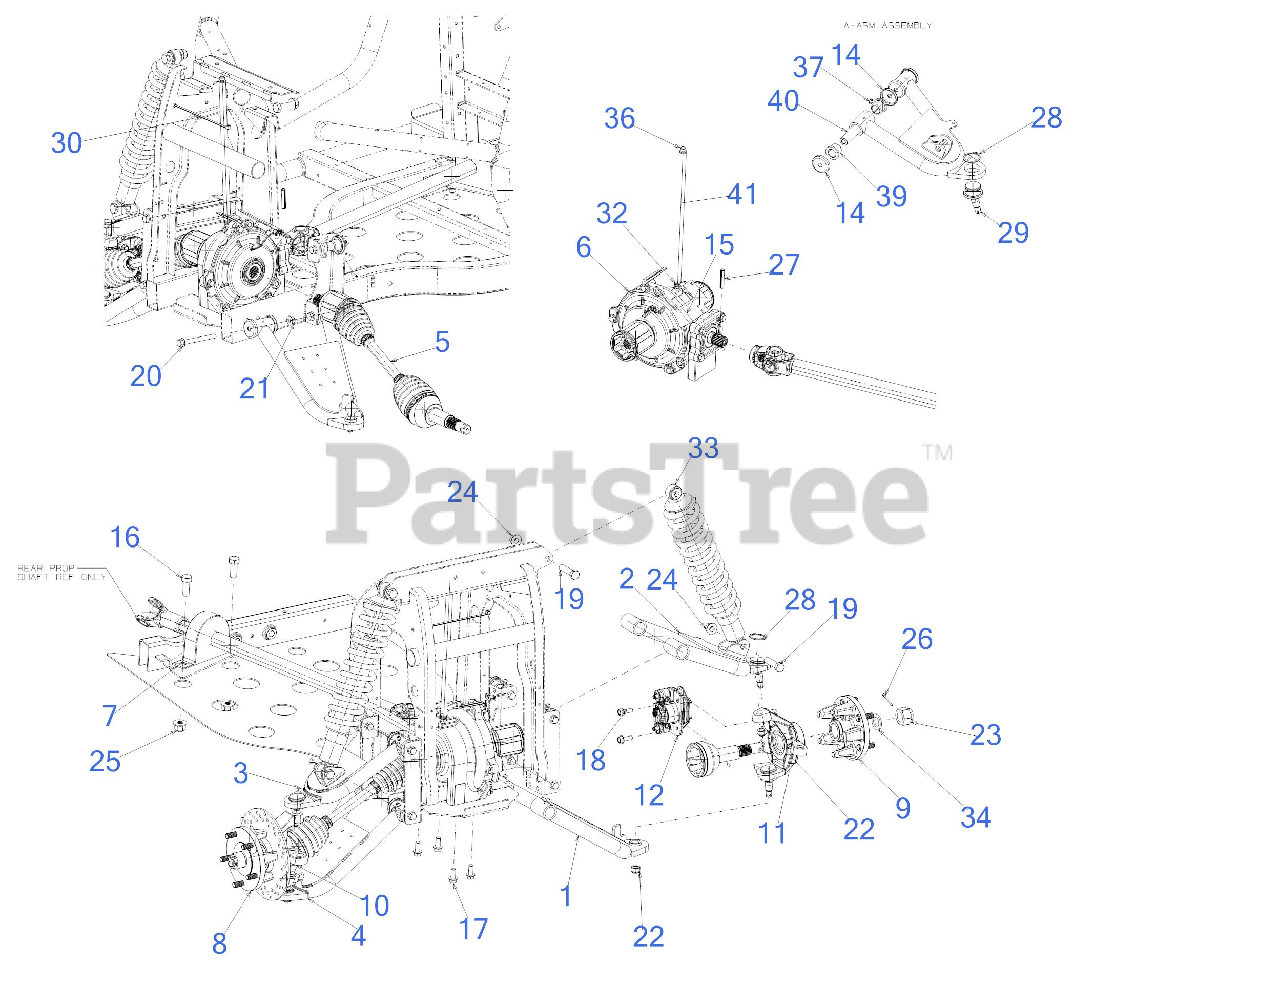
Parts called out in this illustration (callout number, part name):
5	CV AXLE JOINT ASSEMBLY
6	DIFFERENTIAL ASSEMBLY
7	FRONT DRIVE SHAFT ASSEMBLY
8	FRONT HUB ASSEMBLY (RH)
8	DISK BRAKE (8.00X.188)
9	FRONT HUB ASSEMBLY (LH)
9	DISK BRAKE (8.00X.188)
10	FRONT KNUCKLE ASSEMLBY (RH)
11	FRONT KNUCKLE ASSEMBLY (LH)
12	FRONT BRAKE CALIPER ASSEMBLY (RH)
12	FRONT BRAKE CALIPER ASSEMBLY (LH)
14	PIVOT ARM BRACKET
15	FRONT CONTROL MOUNTING BRACKET
16	SCREW M14-2 x 35 GR8
17	SCREW 3/8-16 x .875 GR5
18	SCREW M8 x 1.25 x 25MM GR8.8
19	SCREW 1/2-13 x 2 GR5
20	HEX FLANGE BOLT 3/8-16:3.50
23	SLOTTED NUT22X1.5
25	LOCK NUT - M14-2
26	COTTER PIN
27	ROLL PIN (5/16-1.75)
28	RETAINING RING
29	BALL JOINT
30	7" CABLE TIE
32	HOSE CLAMP
33	FRONT SHOCK ABSORBER
34	THRUST WASHER
37	GREASE FITTING
39	FLANGE BEARING .75 X .993
40	SPACER .385 X .75 X 1.873
41	HOSE LOW PERMEATION
